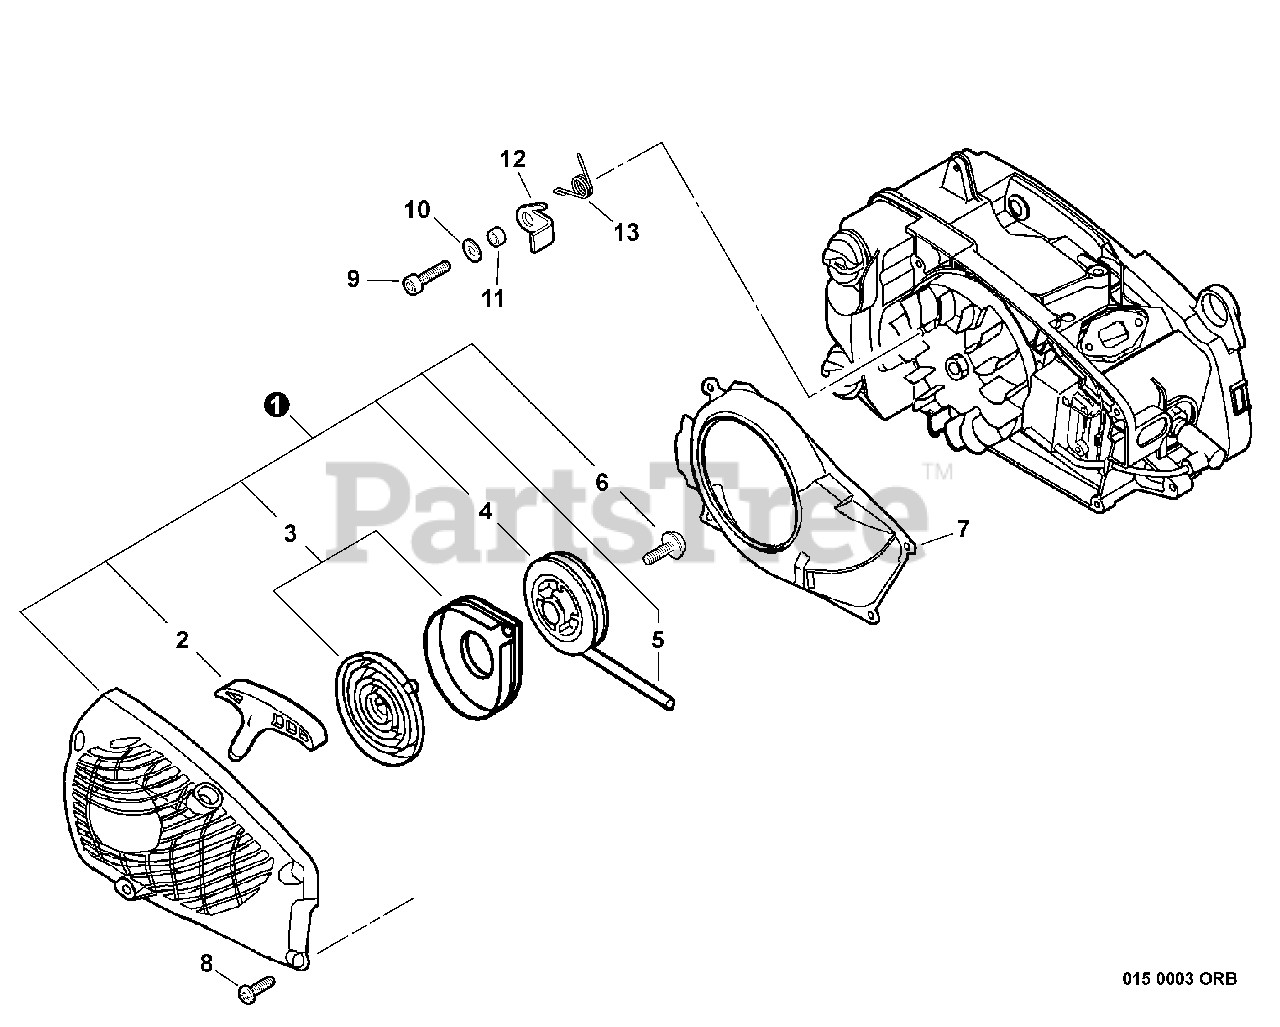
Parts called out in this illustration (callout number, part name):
1	STARTER ASSY, RECOIL - ORANGE
2	GRIP, STARTER
3	SPRING SET, RECOIL
4	REEL, ROPE
5	ROPE, STARTER
6	SCREW
7	COVER, FAN
9	BOLT 5×14
10	WASHER 5.5×12×0.8
11	SPACER 5.2×8×2.1
13	SPRING, TORSION
